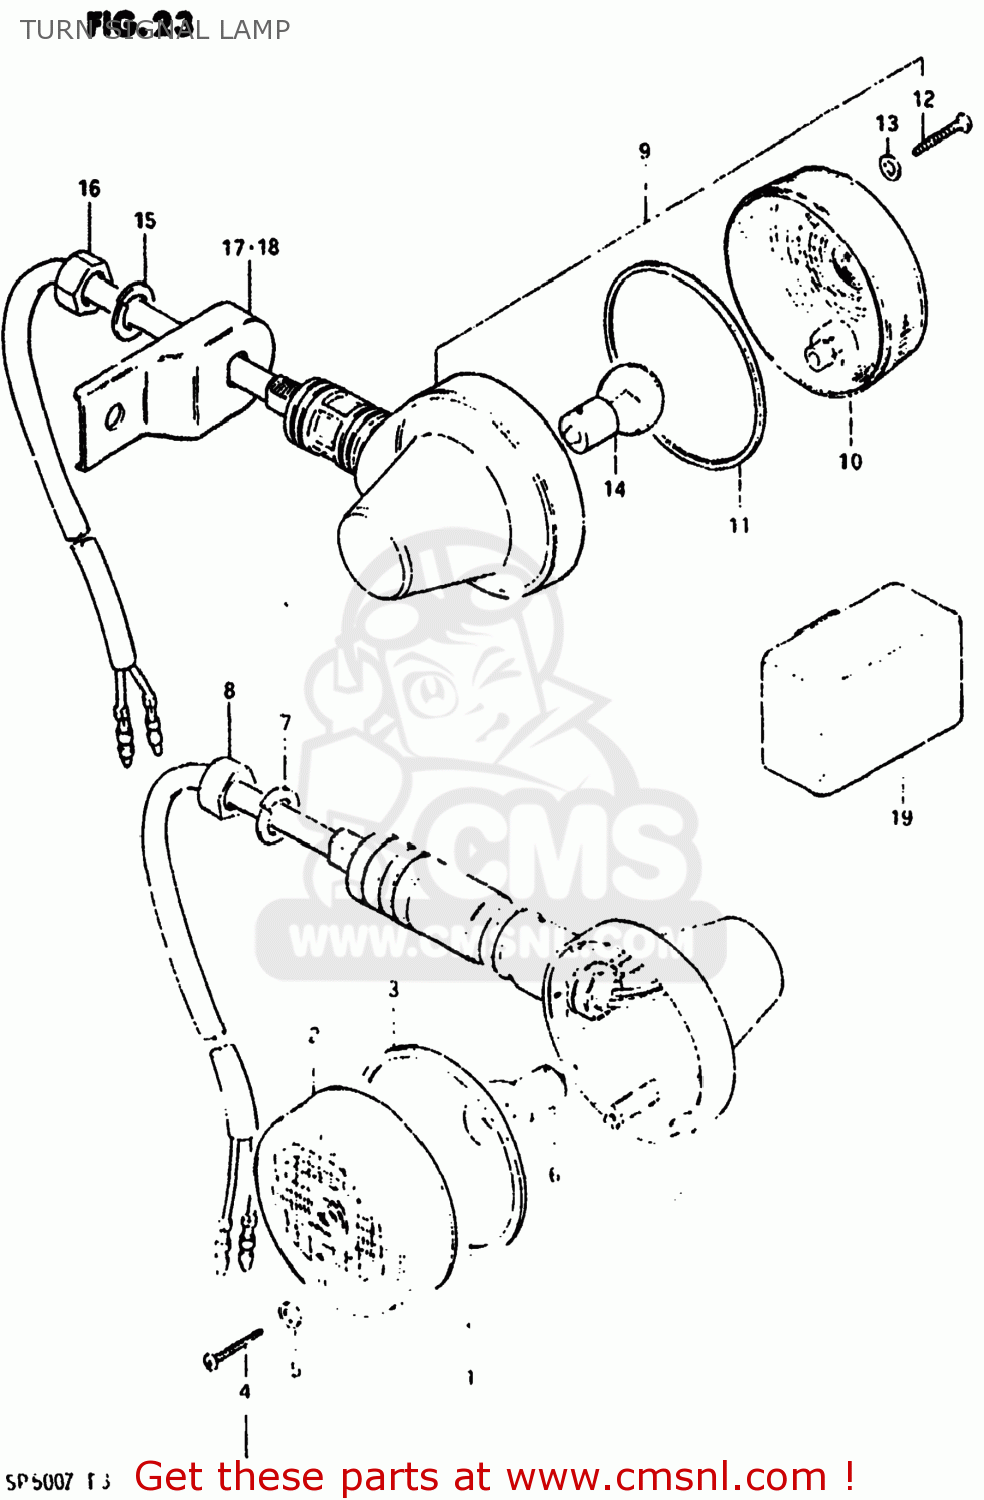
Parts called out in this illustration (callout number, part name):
1	LAMP ASSEMBLY,FRONT TURN SIGNAL
2	LENS
3	GASKET (NAS)
4	SCREW TAPP.
5	GASKET (NAS)
6	BULB(6V17W,STANLEY,A4513A)
7	WASHER,LOCK 12
8	NUT
9	LAMP ASSY,RR TURNSIGNAL
10	LENS
11	GASKET (NAS)
12	SCREW TAPP.
13	GASKET (NAS)
14	BULB(6V17W,STANLEY,A4513A)
15	WASHER,LOCK 12
16	NUT
17	BRACKET,REAR TURN SIGNAL
18	BRACKET,REAR TURN SIGNAL
19	RELAY,TURN SIGNAL
